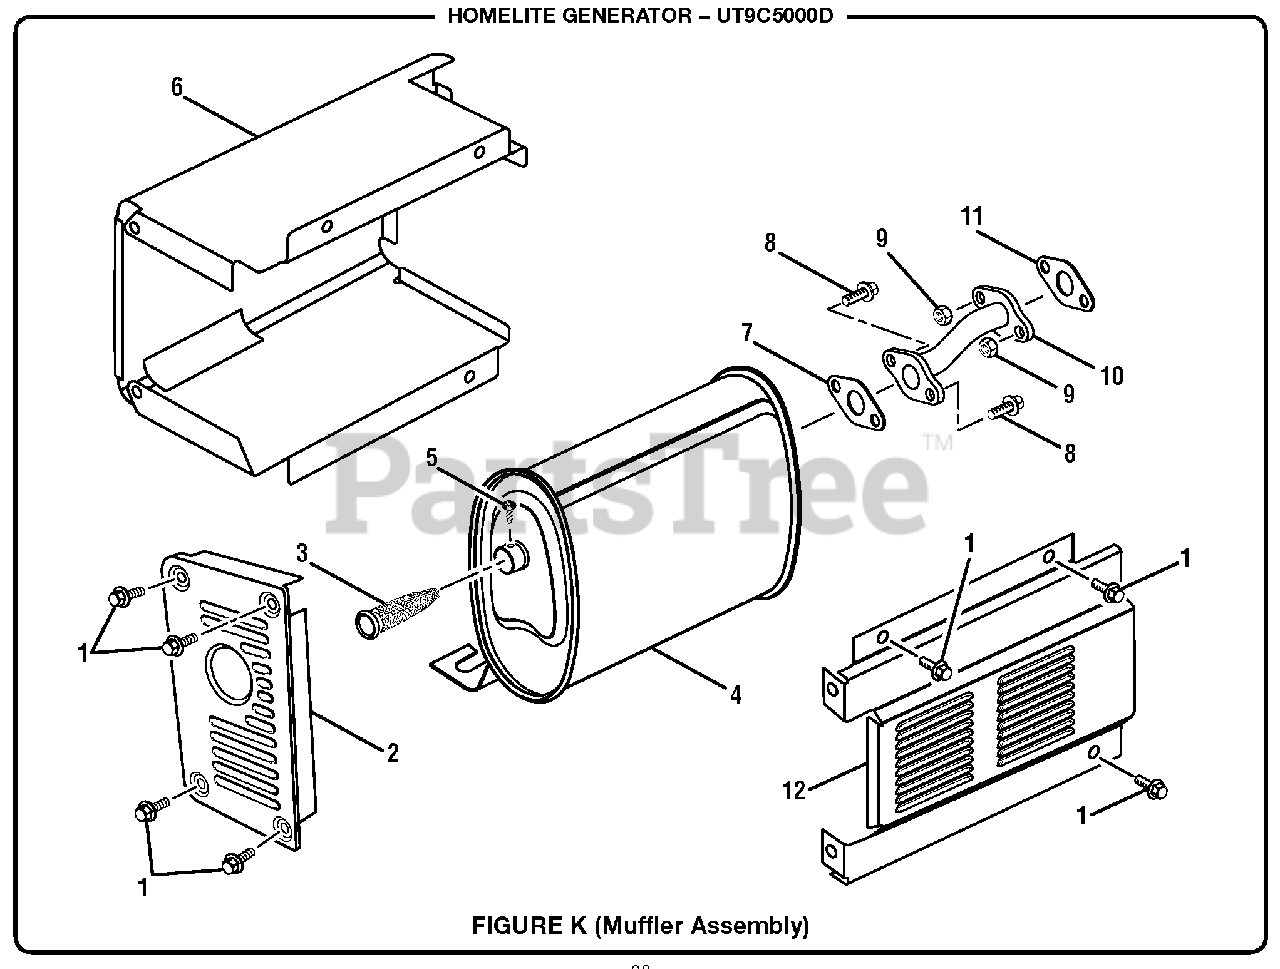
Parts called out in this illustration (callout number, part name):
1	Bolt (M8 x 16 mm, Flange Hd)
2	Side Cover
3	Spark Arrestor
4	Muffler Assembly
5	Set Screw
6	Inner Cover
7	Exhaust Gasket (Engine)
8	Flange Bolt (M8 x 25 mm)
9	Hex Nut (M8)
10	Manifold (Exhaust)
11	Gasket (Exhaust, Muffler Side)
12	Outer Cover
